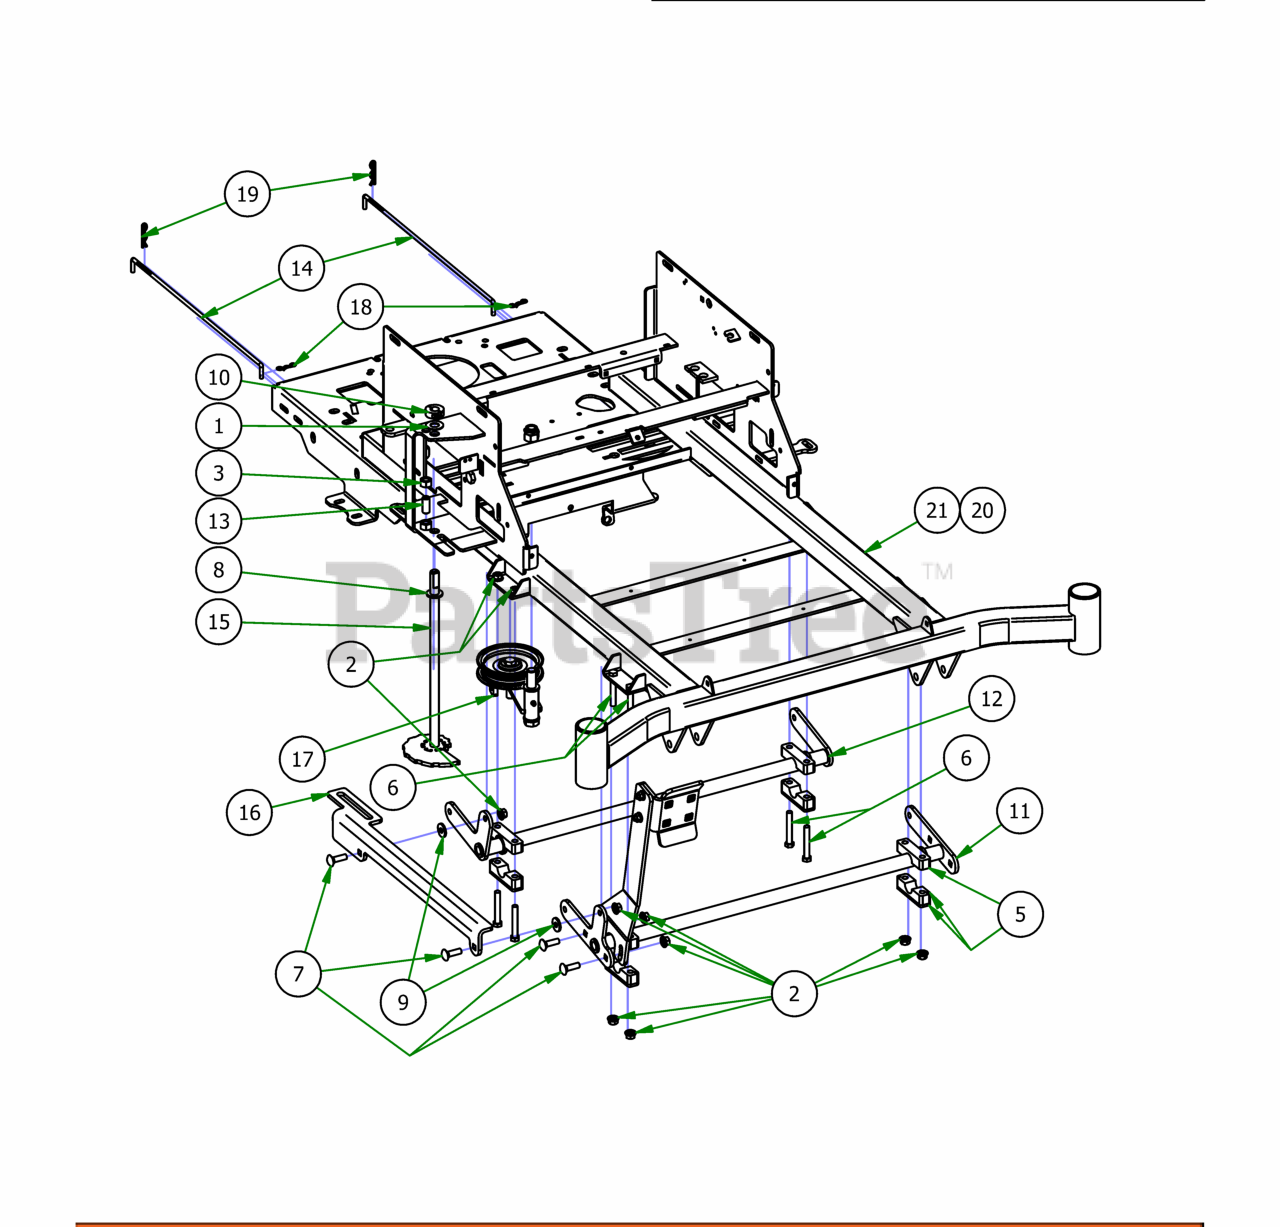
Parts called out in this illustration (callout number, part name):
1	.625 ID x 1.250 OD x .062 THK F/W Nylon
2	3/8-16 NYLON INSERT FLANGE LOCKNUT (GR.F) ZINC
3	1/2" Hex Nut
4	1/2-13 NYLON INSERT FLANGE LOCKNUT ZINC
5	Pillow Block Kit
6	3/8-16 x 2 1/2" Hex Bolt
7	3/8-16 X 1-1/4 CARRIAGE BOLT ZINC
8	.630 ID x 1.122 OD x .142 THK Plastic Washer
9	.360 ID Plastic Washer
10	5/8" Split Collar
11	Actuator Bar Front- 2017 MZ/ZT
12	Actuator Bar Rear- 2017 MZ/ZT
13	Dial Rod Plunger
14	Neutral Rod
15	ZT Deck Height Bar Assembly
16	2017 MZ/ZT Actuator Linkage
17	ZT Pump Idler
19	Neutral Rod Clip
20	ZT 54" and 60" Frame
21	2017 MZ/ZT 54"-60" Frame
